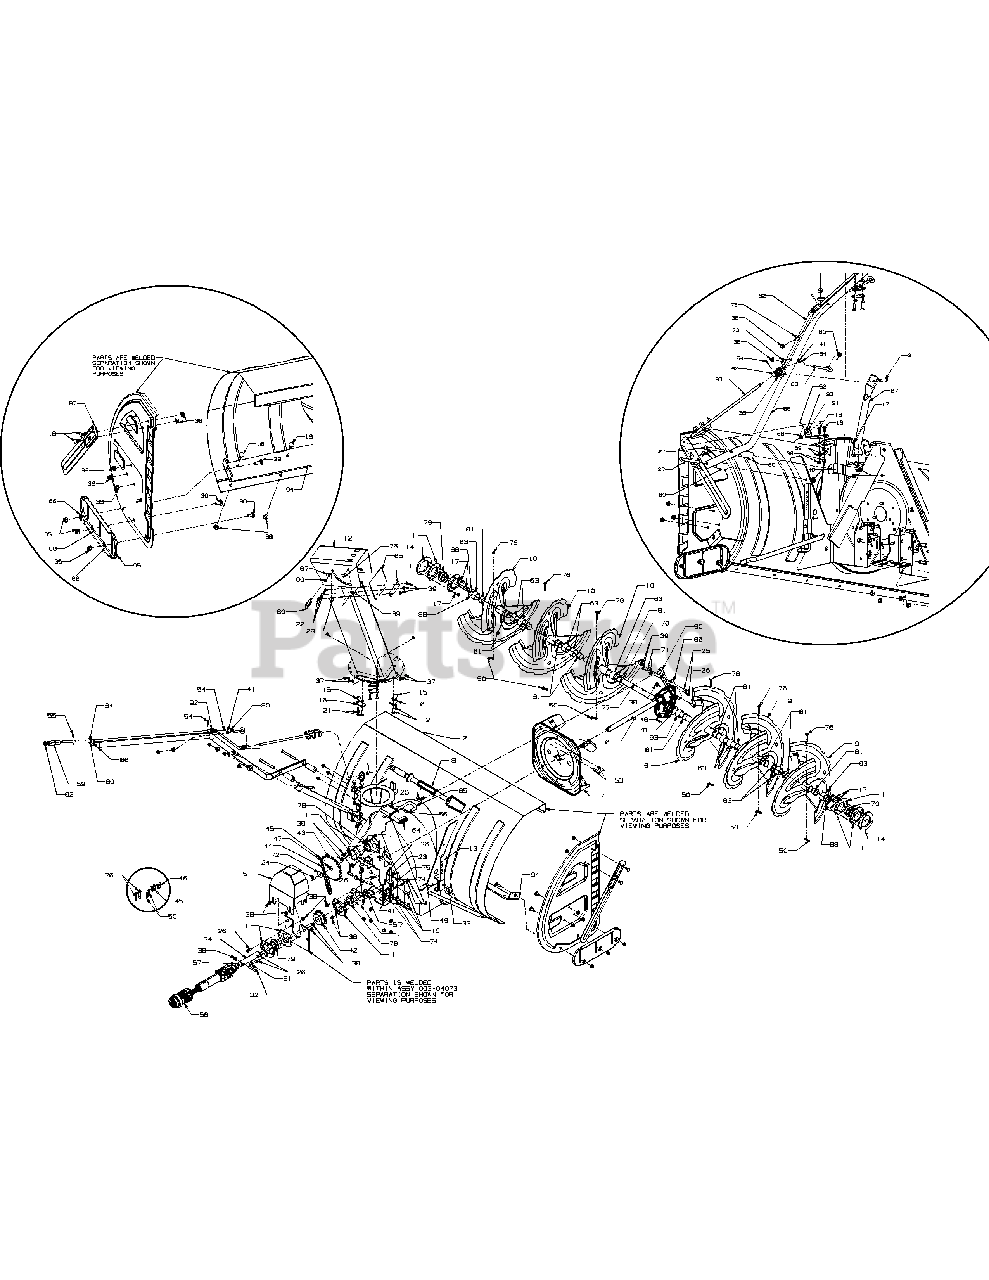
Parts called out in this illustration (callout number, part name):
1	Bearing Housing
2	Housing Assembly
3	Chute Assembly
4	Bracket Assembly
6	Auger Gear Assembly
7	Impeler Assembly
8	Chute Cleanout Tool
8	Chute Cleanout Tool Mount
9	Spiral Assembly, RH
10	Spiral Assembly, LH
11	Rubber Chute Bracket
12	Chute Deflector
13	Stand Bracket
14	Spacer Plate
15	Chute Clamp Spacer
16	Chute Clamp
17	Hex Screw, 5/16-18 x 1.00
18	Carriage Bolt, 5/16-18 x .750
19	Hex Screw, 3/8-16 x 1.00
20	Hx. Wshr. Screw, 5/16-20 x .750
21	Carriage Screw, 1/4-20 x 1.00
22	Machine Screw, 1/4-20 x .625
23	Hex Screw, 5/16-18 x 3.50
24	Hex Screw, 5/16-18 x .75
25	Hex Screw, 1/4-20 x .75
26	Hex Screw, 5/16-18 x .875
27	Hex Screw, 3/8-16 x 3.50
28	Carriage Bolt, 5/16-18 x .875
29	Carriage Bolt, 3/8-16 x 1.00
30	Carriage Bolt, 3/8-16 x .75
31	Hex Screw, 5/16-18 x 1.75
32	Hex Screw, 5/16-18 x 1.75
33	Clevis Pin
35	Hex Lock Nut, 3/8-16
36	Jam Nut, 1/4-20
37	Hex Lock Nut, 1/4-20
38	Hex Jam Lock Nut,5/16-18 GR8
39	Flange Lock Nut, 1/4-20
40	Flange Lock Nut, 3/8-16
41	Hex Nut, 5/16-18
42	Sprocket 15 tooth
42	Sprocket 13 tooth
44	Roller Chain
45	Chain Connecting Link
46	Chain Half Link
47	Hi-Pro Key
48	Woodruff Key
49	Click Pin
50	Bow-Tie Cotter Pin
51	Hi-Pro Key
52	Cotter Pin
53	Spirol Pin, 5/16-1.75
54	Spirol Pin, .125 x .812
55	Roll Pin, 1/8 x .63
56	Spirol Pin
57	Snap Ring
58	Repair Kit, Yoke Lock
59	Chute Crank Knob
60	Wing Nut
61	Push Cap
63	Spcer., 1.50 OD x 1.00 ID x 1.00
64	Compression Spring, .57 x 2.09
65	Rubber Deflector
66	Washer, .401 x .870 x .063
67	Flat Washer, .349 x 1.16 x .064
68	Flat Washer, .385 x .62 x .063
69	Bell Washer, .340 x .872 x .060
70	Flat Washer, 1.00 x 1.75 x .107
71	Bell Washer, .265 x .75 x .062
72	Flat Washer, .330 x 1.25 x .120
73	Saddle Wshr., .320 x.93 x .060
74	Flat Washer, .36 x .93 x .110
75	Shoulder Screw, .375 x .181
76	Shear Pin, .25 x 1.75
77	Spiral Axle
78	Self-Aligning Bearing
79	Self-Aligning Bearing
80	Plastic Bushing
81	Flnge. Bshg., 1.05 ID x 1.16 OD
82	Chute Crank Rod
83	Eye Bolt, 5/16-18 x 3.0
84	Chute Crank Rod, .375 x 36.75
85	Front Hitch Pin
86	Crank Support Tube
87	Support Tube
88	Spacer, 1.004 x 1.375 x .25
89	Spacer, 3/8 ID x 1.0 x 2.25
90	Gear Housing Support Bracket
91	Chute Crank Bracket
92	Bracket Assembly Joint
93	Chute Crank Assembly
94	Shave Plate
95	Skid Shoe
96	Support Plate
97	Blade Guide
